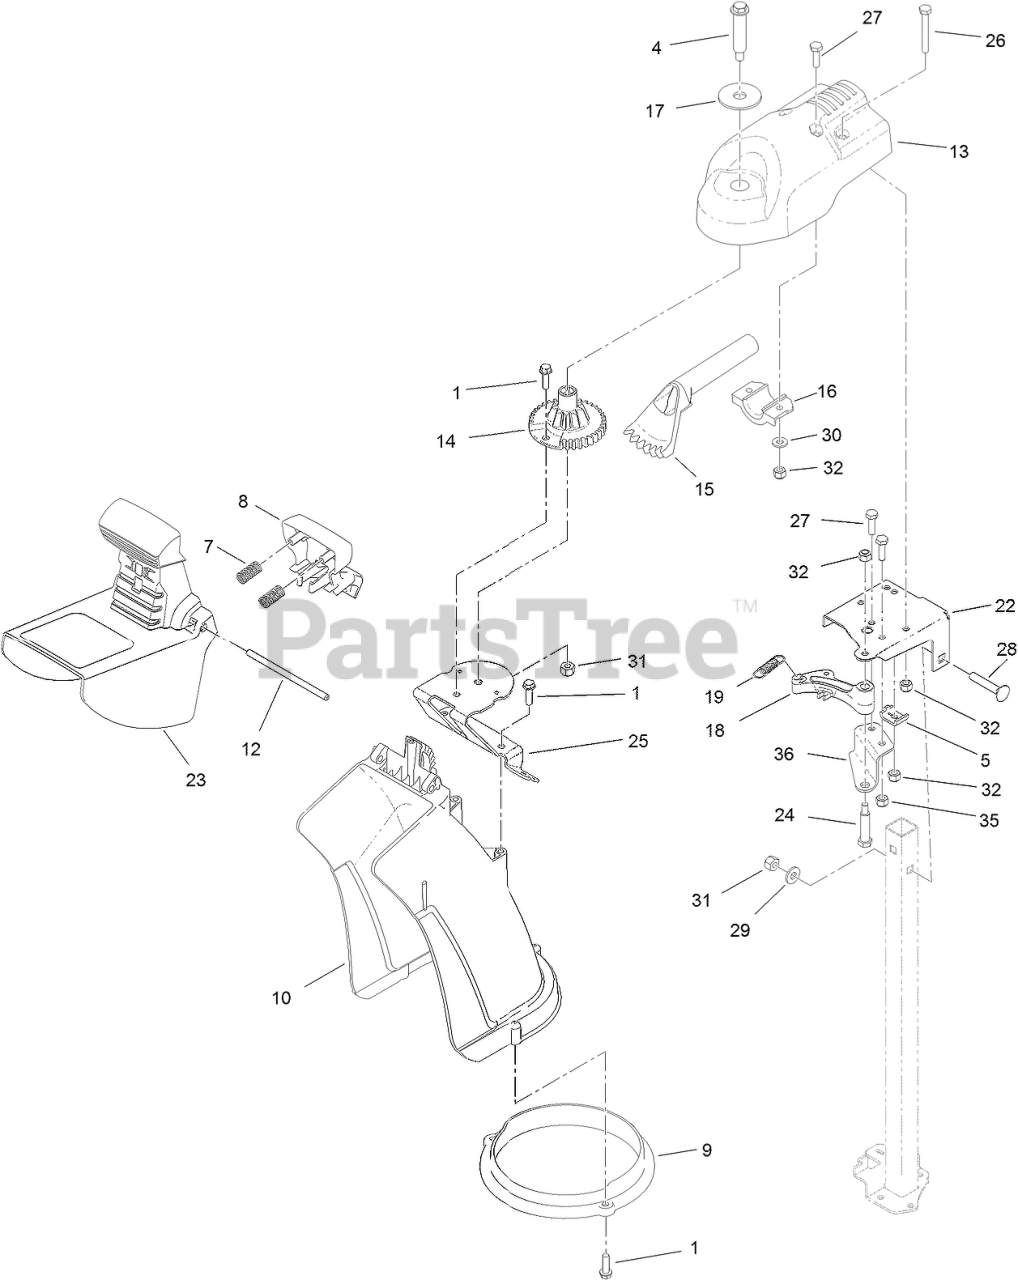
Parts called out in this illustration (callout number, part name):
1	SCREW-HWH
4	BOLT-SHOULDER
5	CLAMP-CABLE
7	SPRING-COMPRESSION
8	TRIGGER-DEFLECTOR
9	RING-CHUTE
10	CHUTE-DISCHARGE
12	ROD-COVER
13	MOUNT-CHUTE, DISCHARGE
14	GEAR-CHUTE
15	GEAR-BEVEL
16	MOUNT-GEAR, BEVEL
17	WASHER-FLAT
18	LATCH-CHUTE
19	SPRING-LATCH, CHUTE
22	BRACKET-SUPPORT, CHUTE
23	DEFLECTOR-CHUTE
24	BOLT-SHOULDER
25	BRACKET-MOUNT, CHUTE
26	SCREW-HH
27	SCREW-HH
28	SCREW-CARR
29	WASHER-FLAT
30	WASHER-FLAT
31	NUT-LOCK, NI
32	NUT-LOCK, NI
35	NUT-LOCK, NI
36	BRACKET-SUPPORT, LATCH
